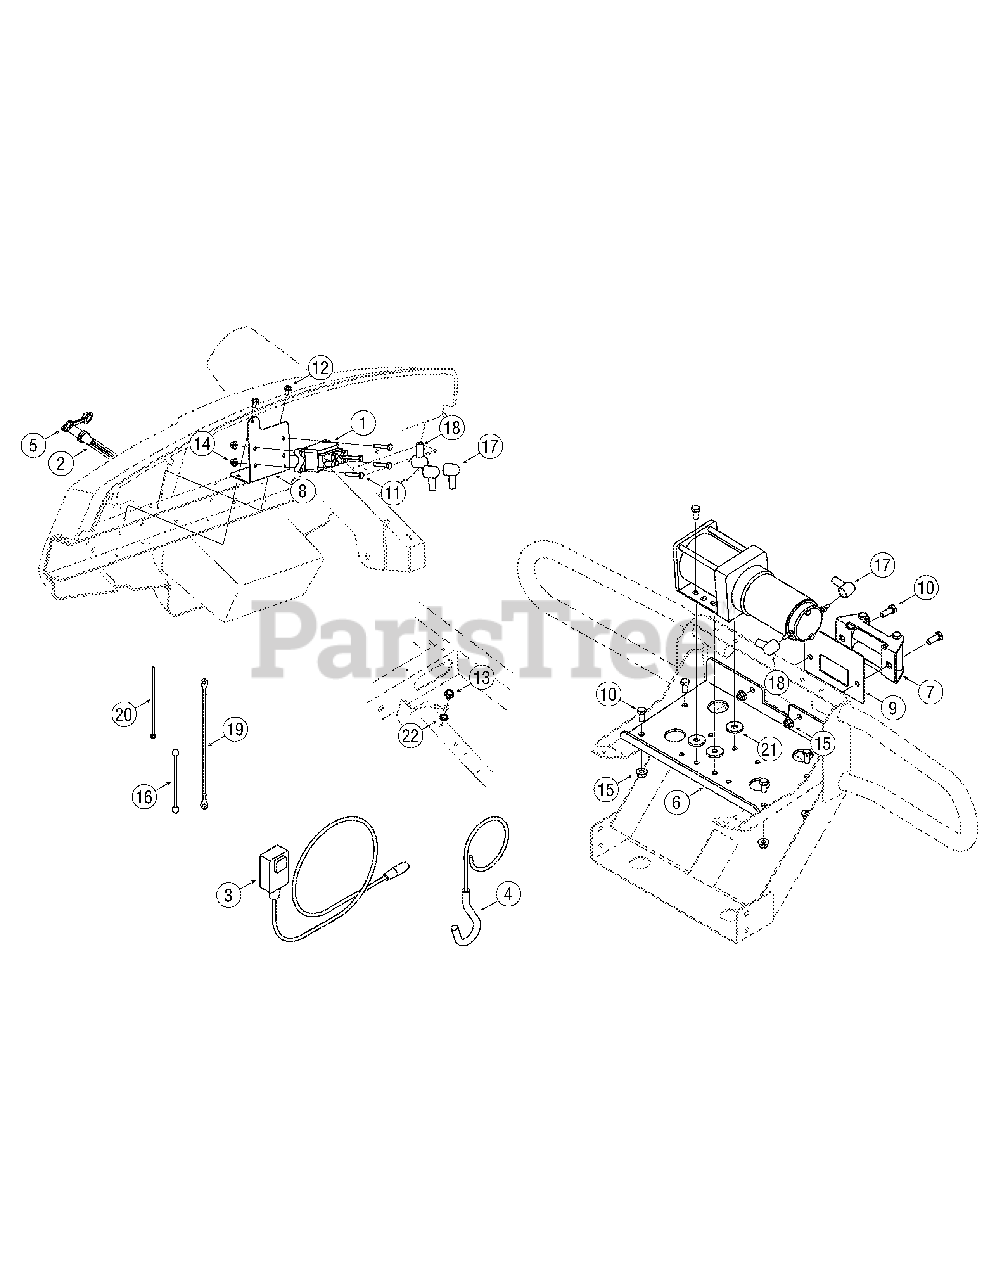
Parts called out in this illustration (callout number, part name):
1	Solenoid Assembly w/Cable
2	Connector/Harness
3	Remote Control
4	Cable Assembly w/Hook
10	Hhcs, 3/8-16 x 1.00
11	Hhcs, 1/4-20 x 1.00
12	Scr, tt, 1/4-20 x .500
13	Scr, tt, 5/16-18 x .500
14	Nut, flglk, 1/4-20
15	Nut, flglk, 3/8-16
16	Cbl, Bat, Winch, red
17	Cvr, Battery
18	Boot, Battery
19	Wire, ground, dsl eng
20	Tie, cbl
21	Washer, flat, .406 x 1.25 x .157
22	Wash, lock, 5/16
